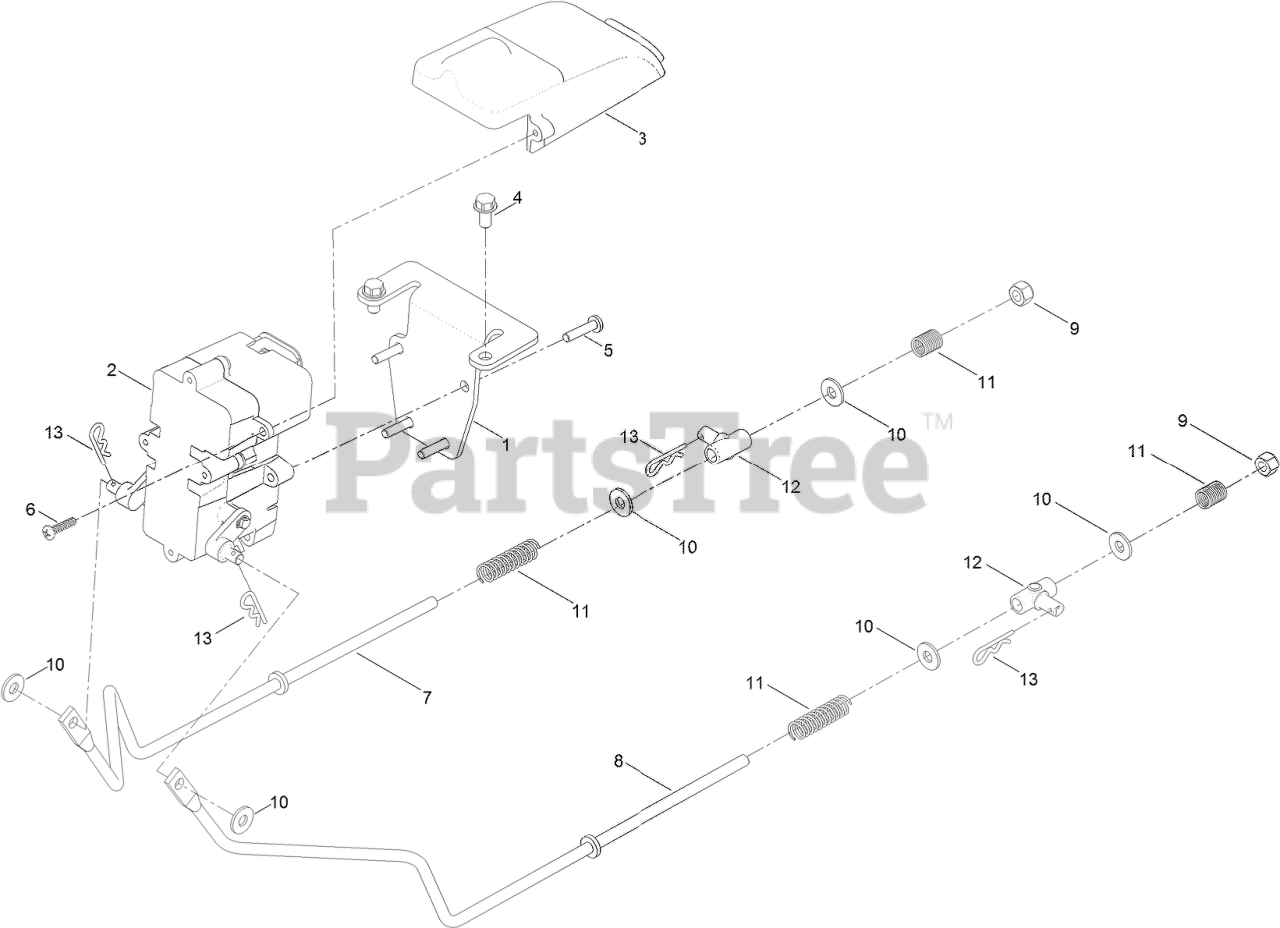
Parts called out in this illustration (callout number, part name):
1	BRACKET-MOUNT, BRAKE
2	BRAKE BOX ASM
3	COVER-CONNECTOR
4	SCREW-HWH
5	SCREW-PPH
6	SCREW-PPH
7	ROD-BRAKE, RH
8	ROD-BRAKE, LH
9	NUT-LOCK, NI
10	WASHER
11	SPRING-COMPRESSION
12	MOUNT-PIVOT
